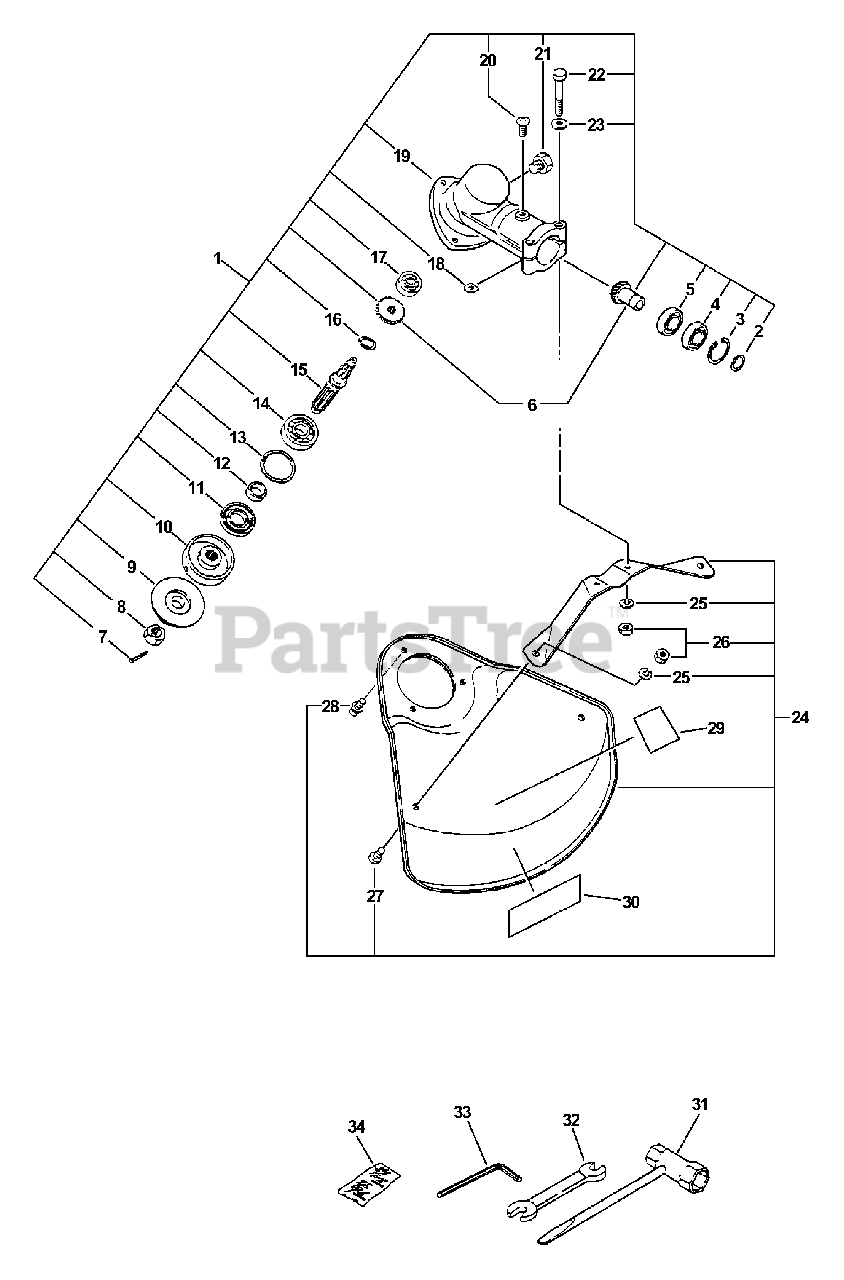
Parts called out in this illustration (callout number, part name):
1	GEAR CASE ASSY
2	RING, RETAINING - 10
3	RING, RETAINING - 22
4	BEARING, BALL - 6900Z
5	BEARING, BALL - 6900
6	GEAR SET - BEVEL
7	PIN, SPLIT - 2X22
8	NUT - 10 -- LEFT HAND
9	ADAPTOR, BLADE - LOWER
10	ADAPTOR, BLADE - UPPER
11	SEAL, OIL
12	RING, RETAINING - 32
14	BEARING, BALL - 6201
15	GEAR - SHAFT
16	RING, RETAINING - 12
17	BEARING, BALL - 609
19	CASE, GEAR
20	SCREW - 5X10
21	BOLT - 8X8
22	BOLT - 5X35
23	WASHER - 5
24	DEBRIS SHIELD KIT - METAL
25	LOCKWASHER - 5
27	SCREW - 5X8
28	SCREW - 5X10
29	LABEL - ECHO
30	LABEL - DANGER
31	T-WRENCH - 17X19mm
32	SPANNER - 8X10mm
33	HEX KEY - 3mm
34	PIN, SPLIT - 2X22
